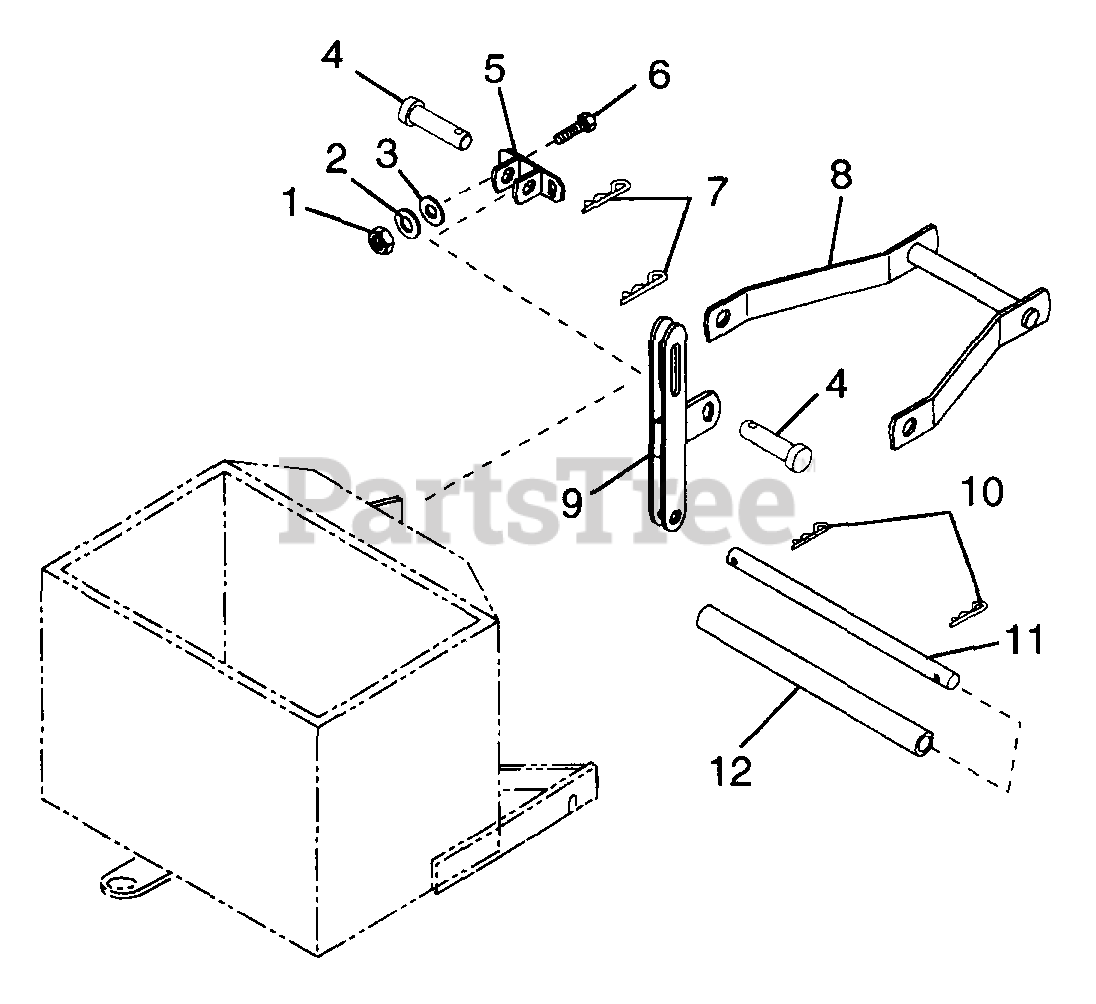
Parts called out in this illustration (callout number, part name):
1	NUT-HEX .375-16
2	WSHR-LK .375X.094 MED PL
3	WSHR-FL-STL .438X1.0X.083 PL
4	PIN-CLEV .619X2.0 YWZC
6	BLT-HEX .38-16X1.00 PL
7	PIN-HAIR INT .14X.4X2.75
8	WEIGHT BOX HANGER
9	BOX SUPPORT
10	PIN-HAIR INT .09X.188 PL
12	TUBE .725 X .875 X 14.00
